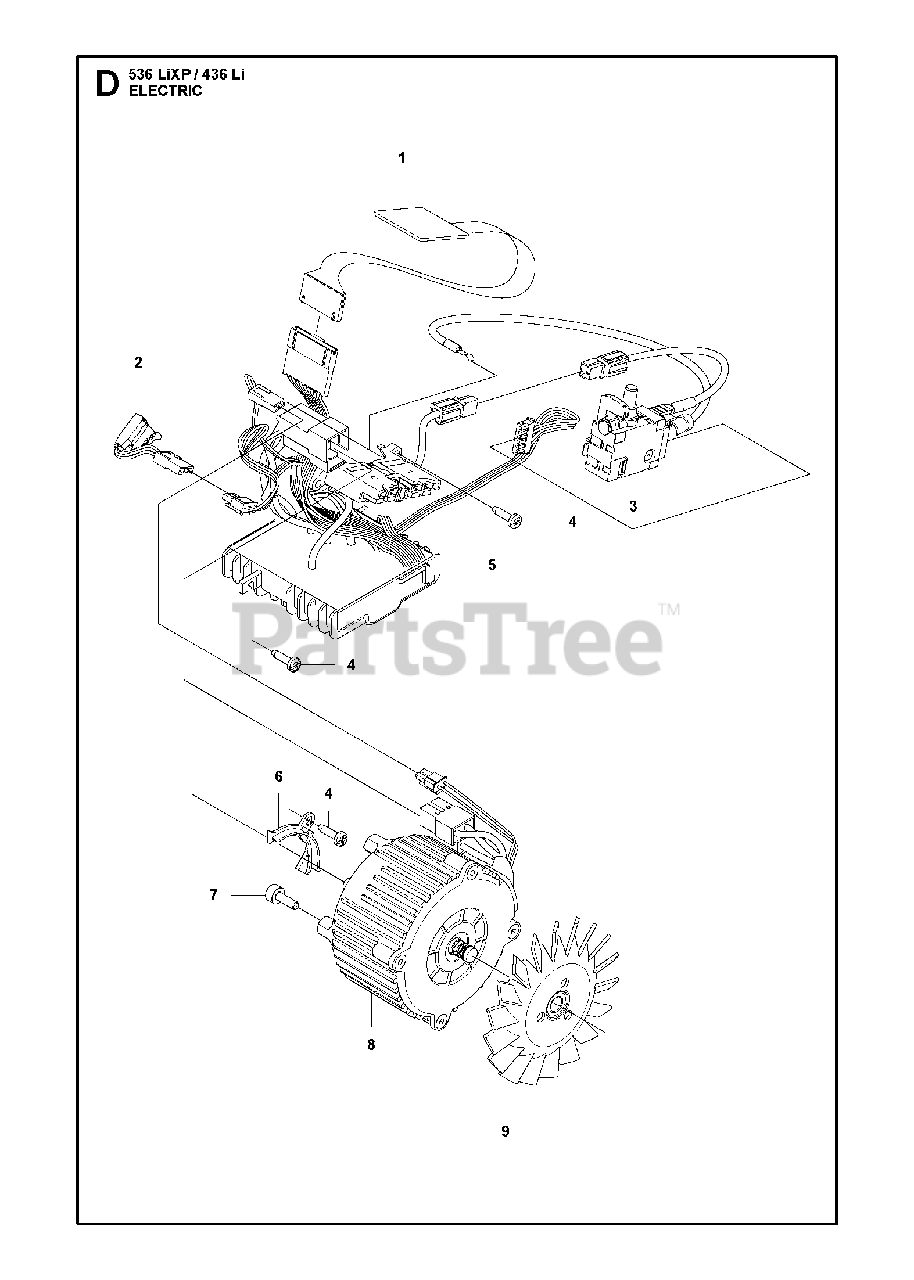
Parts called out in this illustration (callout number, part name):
1	KEY PAD 2 BUTTON TRIMMER DC (T
2	WIRING ASSY
3	WIRING ASSY
5	CONTROL UNIT
8	MOTOR ASSY W/ FAN
